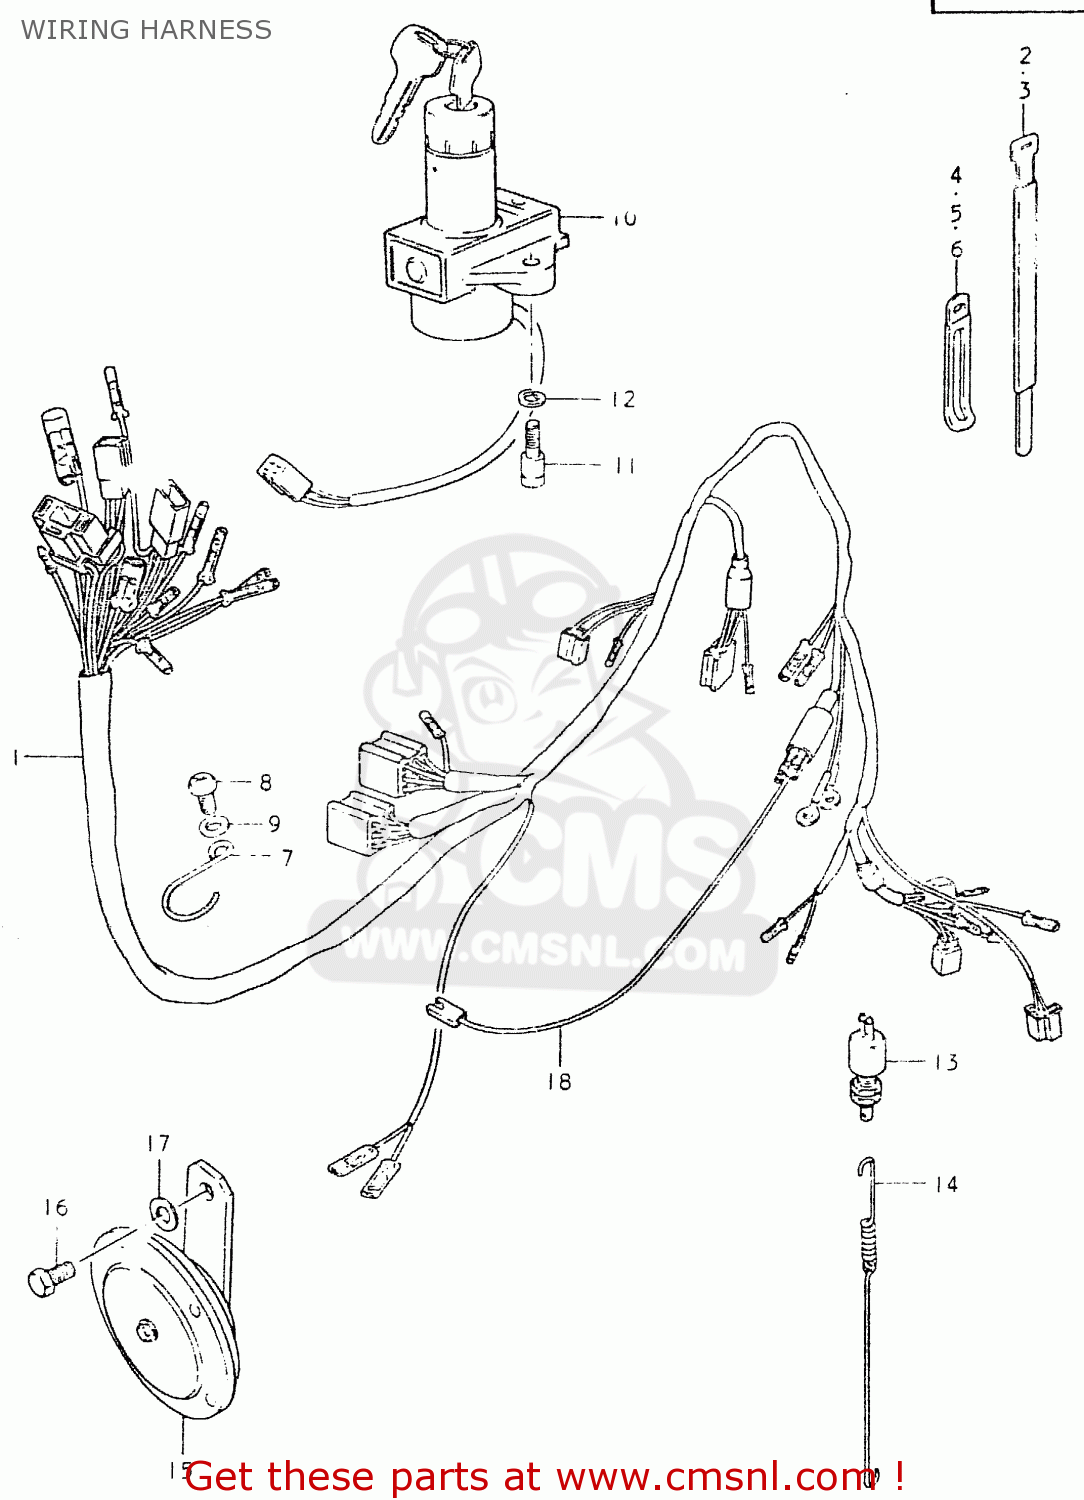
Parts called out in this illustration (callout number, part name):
1	WIRING HARNESS
2	CLAMP
3	CLAMP(L:120)
4	CLAMP
5	CLAMP
6	CLAMP
7	GUIDE,WIRING HARNESS
8	SCREW 6X12
9	WASHER 6MM
10	LOCK ASSEMBLY,STEERING
11	BOLT
12	LOCK WASHER
13	SWITCH ASSY,BRAKE LAMP
14	SPRING
15	HORN ASSEMBLY,LOW PITCH
16	BOLT 8X12
17	WASHER
18	WIRE
